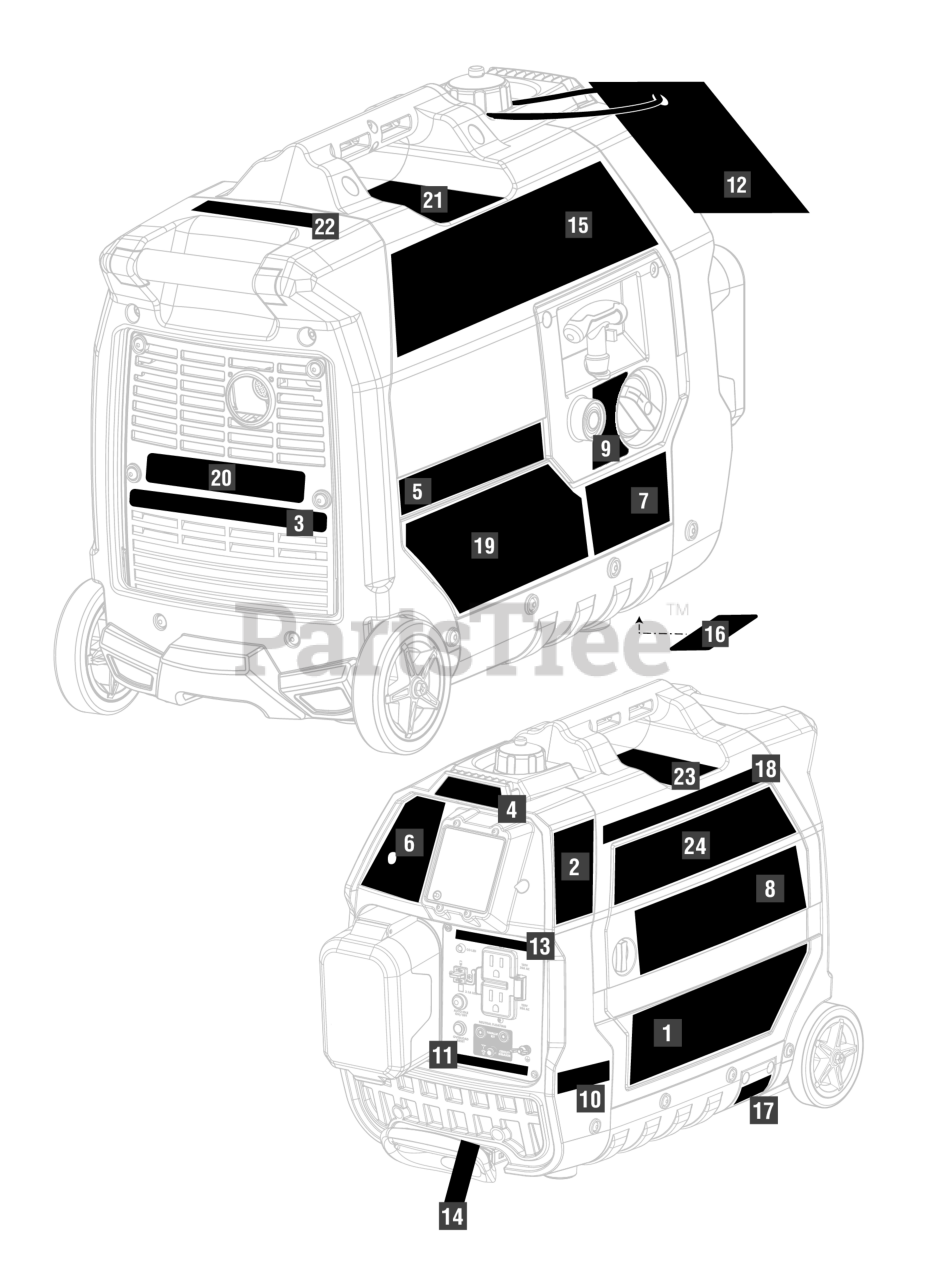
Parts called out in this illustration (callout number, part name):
1	Inquiries Label
2	Fuel Stabilizer Label
3	Ground Warning Label (En/Fr)
4	Logo Label
5	Start Label
6	Electric Start/Bluetooth Hood Label
7	Electric Start Label
8	CO Automatic Shut Down Label
9	Control Knob Label
10	Do Not Tamper Warning Label
11	LED Light Legend Label
12	Warning Hangtag
13	Cable Ties
14	Button Handle Release Label
15	Performance Label
16	Upright Storage Label
17	Internally Placed Maintance Label
18	Fire Distance Label
19	Gen Control/Bluetooth Label
20	Combustion Label
21	Danger Label
22	Exhaust Direction Label
23	CPSC Danger Label
24	Performance Label (Maintenance Door)
